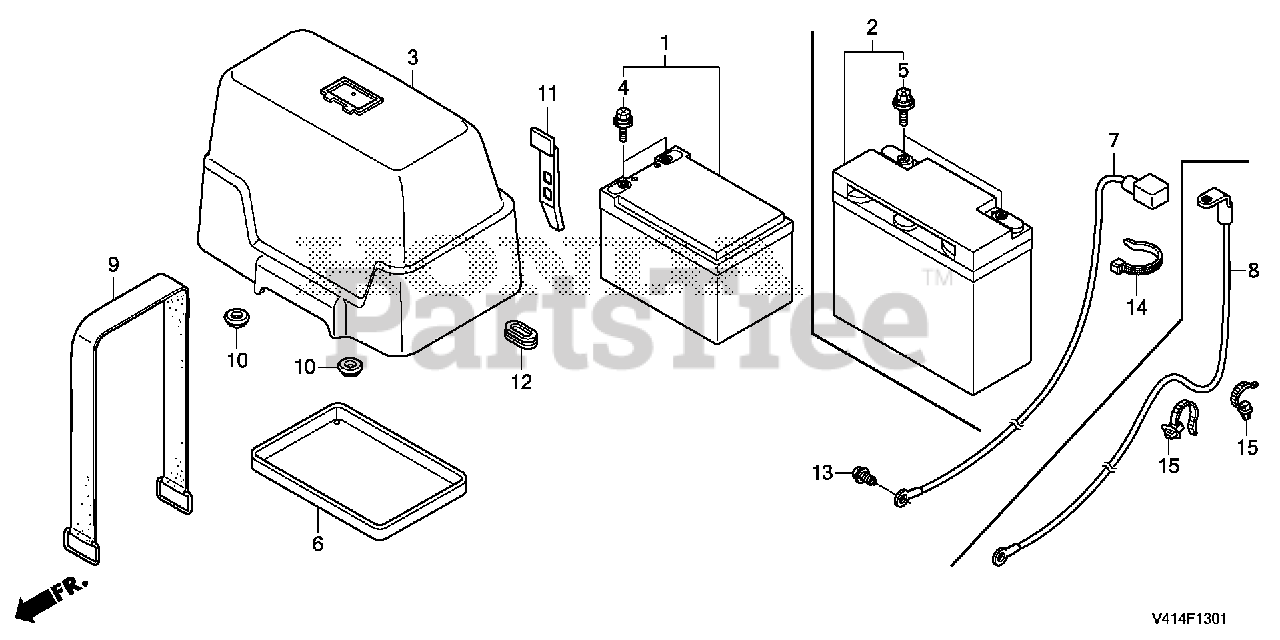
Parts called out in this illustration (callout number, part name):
1	BATTERY (HR12-12) (MSDS)
1	BATTERY (HR12-12) (FOR CALIFORNIA) (MSDS)
3	COVER, BATTERY *NH1* (BLACK)
4	BOLT-WASHER (5X10)
6	RUBBER, BATTERY
7	CABLE ASSY., GROUND
9	BAND, BATTERY
10	GROMMET, COVER
11	BELT, ENGINE COVER
12	GROMMET A, SIDE COVER
13	BOLT, FLANGE (6X12) (CT200)
14	BAND, WIRE (165MM) (BLACK)
